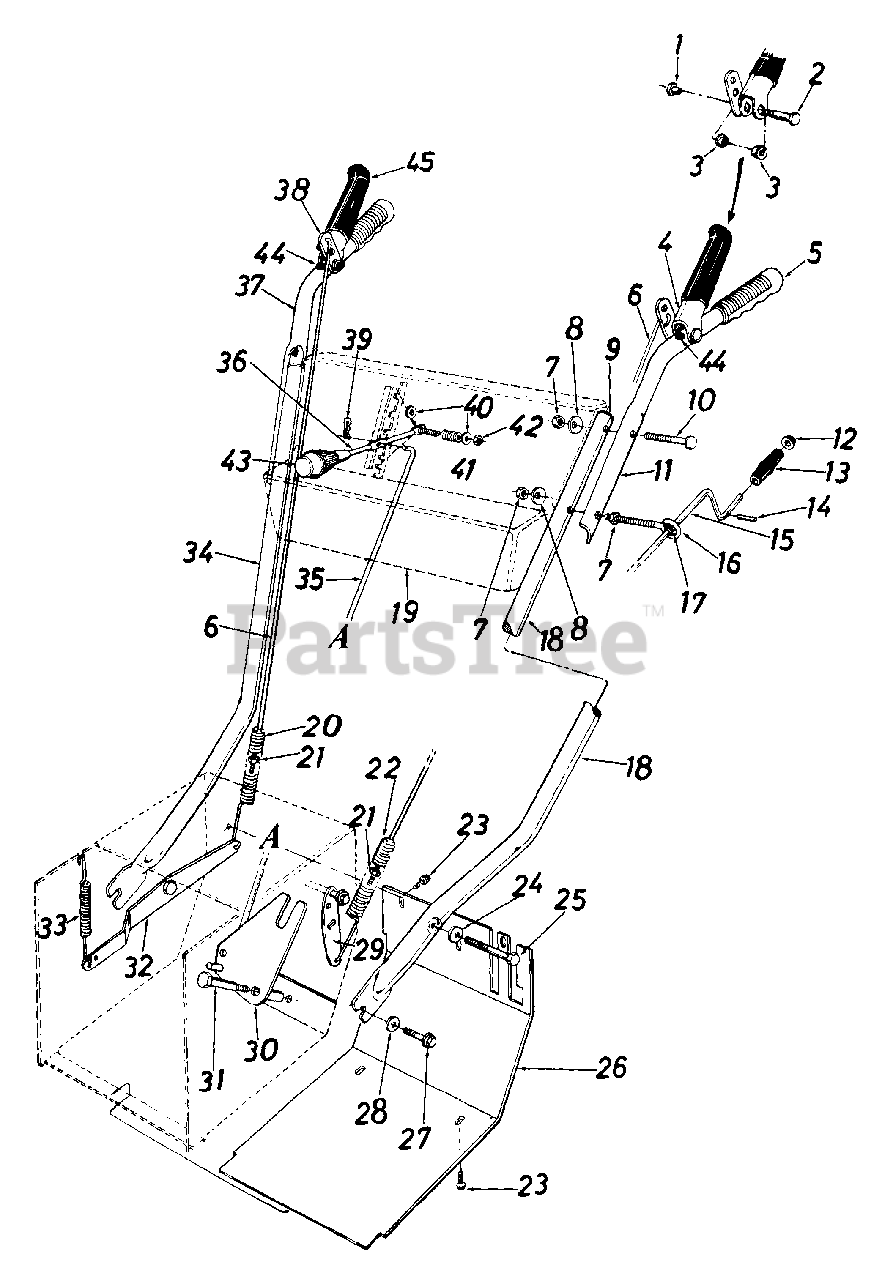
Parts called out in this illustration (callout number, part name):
1	Shld. Nut 1/4-20 Thd.
2	Shld. Bolt .374 Dia x 1.375" Lg.
3	Hex Flange Plastic Bearing .38" I.D
4	Clutch Grip Ass'y.- L.H
5	Grip - Red
6	Lockout Rod
7	Hex Nut 5/16-18 Thd.
8	Bell-Wash. .34" I.D. x .88" 0.D.
9	Plastic Plug
10	Curved Carriage Bolt 5/16-18 x 2.0" Lg.
11	Upper Handle - L.H.
12	Push Nut 3/8" Rod
13	Knob 3/8" Rod
14	Roll Pin .12 Dia. x 631" Lg.
15	Chute Crank Ass'y.
16	Eye Bolt 5/16-18 x 5.0" Lg.
17	Plastic Bushing
18	Lower Handle - L.H.
19	Handle Panel Ass'y.
20	Extension Spring .75" O.D x 5.0" Lg.
21	Hex Ins. L-Nut 1/4-20 Thd.
22	Extension Spring .75" O.D. x 5.0" Lg.
23	Hex Wash Hd. Self-Tap Scr. 5/16-24 x 50" Lg.
24	Bell-Wash. .40" I.D x .88" O.D.
25	Hex Bolt 3/8-16 x 2.0" Lg.
26	Frame Cover
27	Pilot Hex Scr. 3/8-16 x .88" Lg.
28	Bell-Wash. .40" I.D. x .88" O.D.
29	Drive Clutch Brkt. Ass'y.
32	Auger Clutch Brkt.
33	Extension Spring .38" O.D. x 3.18" Lg.
34	Lower Handle - R.H.
35	Shifting Rod
36	Shift Handle
39	Int. Cotter Pin 5/16" Dia.
40	Fl-Wash. .344" I.D. x .62" O.D.
41	Compression Spring
42	Hex Ins. L-Nut 5/16-18 Thd.
44	Push Cap
45	Black Vinyl Grip
